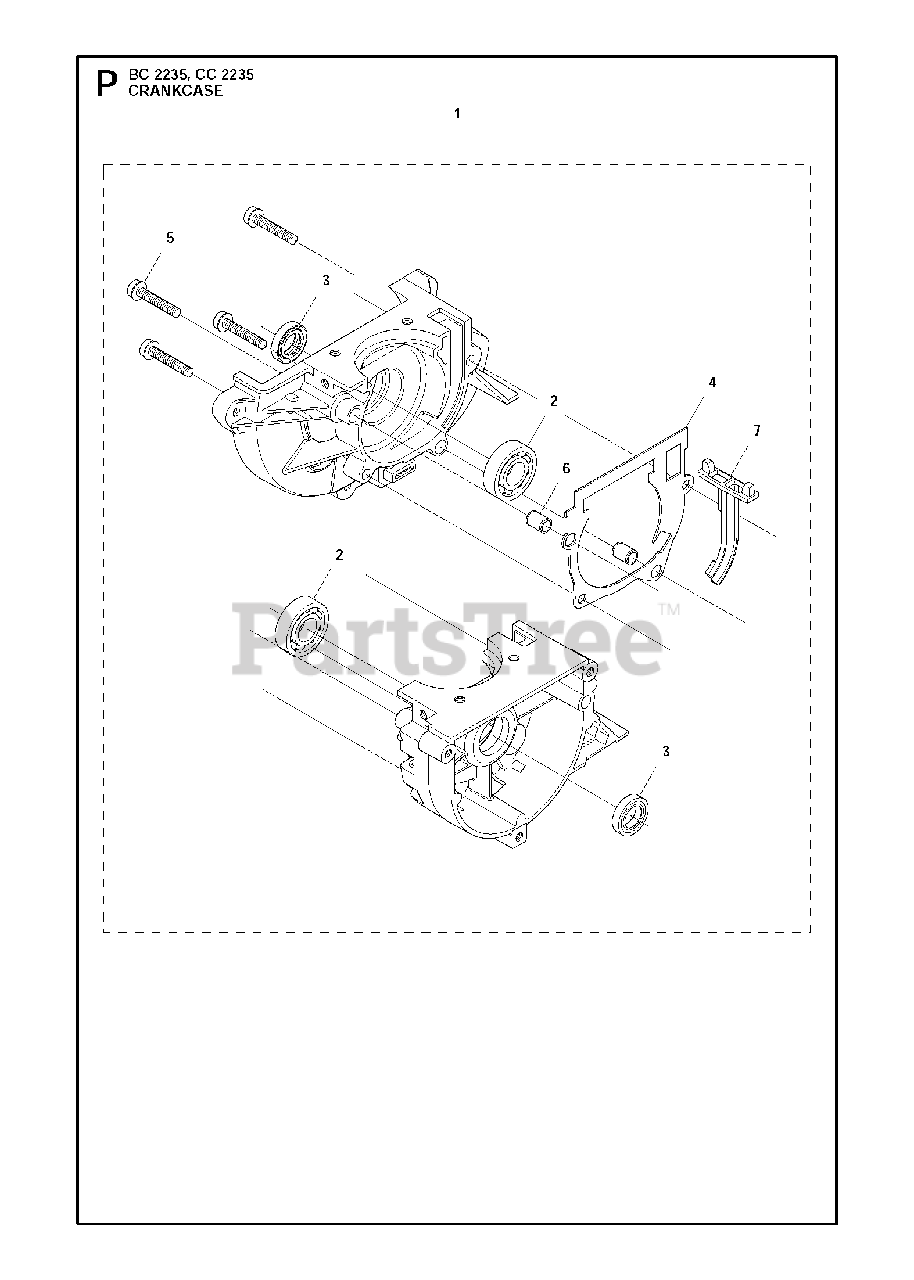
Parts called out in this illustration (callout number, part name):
1	CRANKCASE CPL
2	BALL BEARING
3	SEALING RING
4	GASKET
5	SCREW
6	SLEEVE
7	INSERT, CARTER
